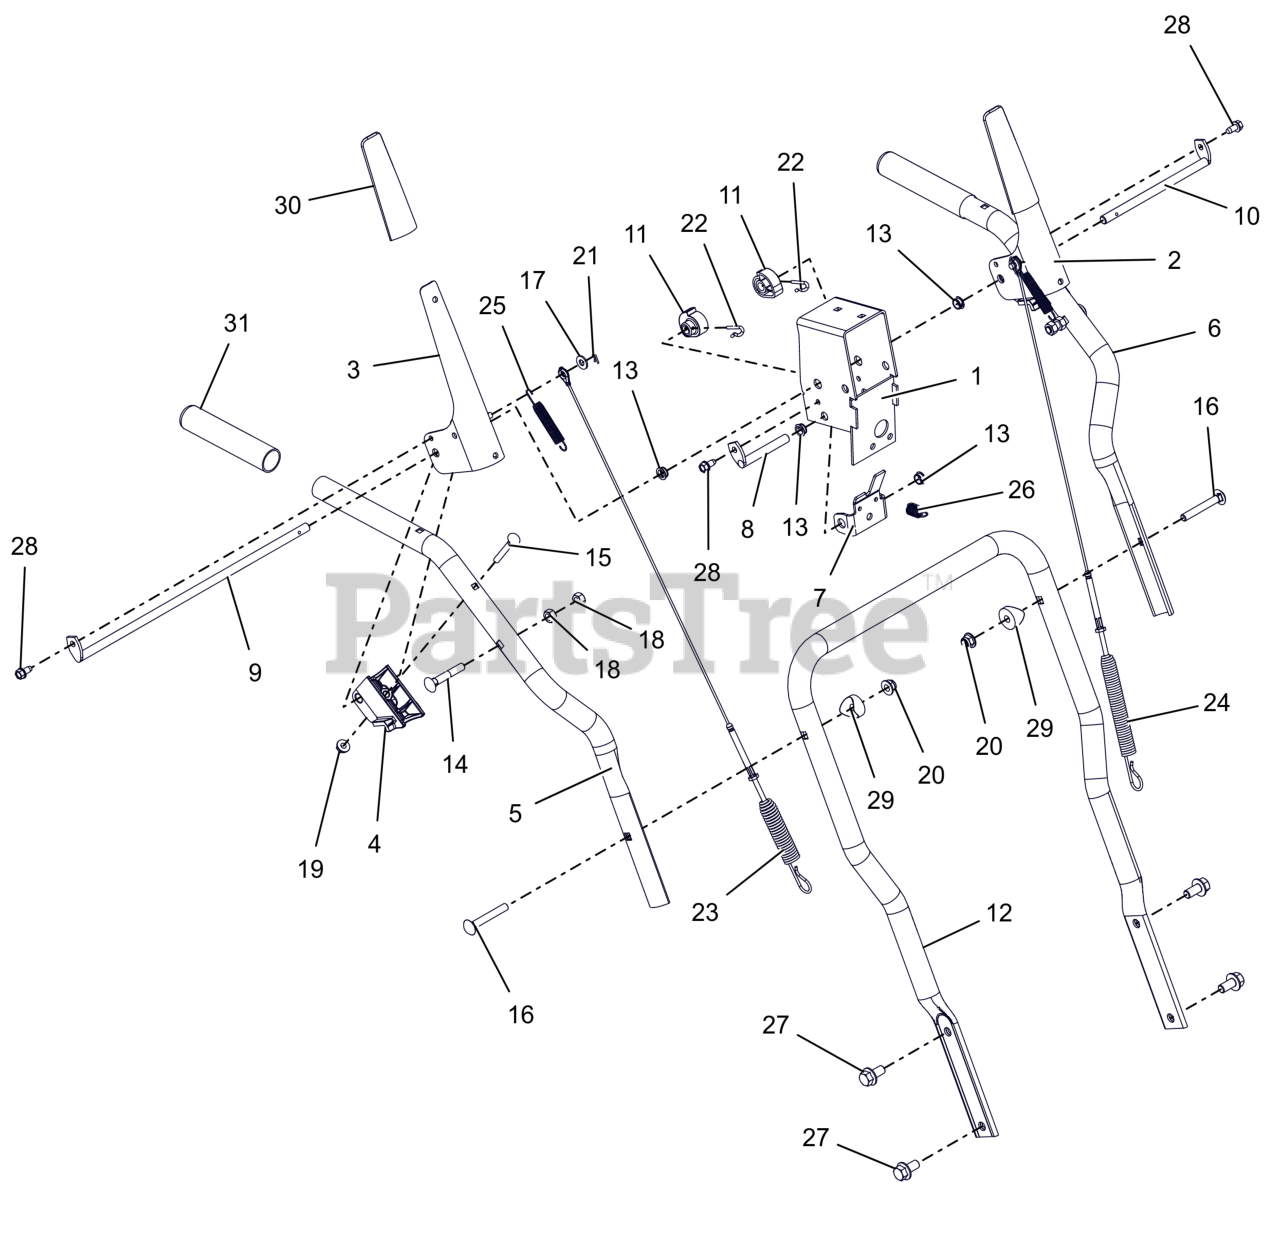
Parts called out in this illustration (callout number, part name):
1	WELDMENT, BRACKET INTERLOCK
2	LEVER, CLUTCH-LH
3	LEVER, CLUTCH-RH
4	BLOCK, CLUTCH PADDLE
5	HANDLEBAR, UPPER - RH (BLACK)
6	HANDLEBAR, UPPER - LH (BLACK)
7	BRACKET, INTERLOCK ARM
8	ROD, PIVOT - INTERLOCK
9	ROD, PADDLE MOUNT - LONG
10	ROD, PADDLE MOUNT - SHORT
11	CAM, INTERLOCK
12	HANDLEBAR, LOWER SMALL DASH (BLACK)
13	BUSHING, POLYLINER-.38 SNAPIN
14	BLT-RDHDXLSQNK .31-18X2.0 G5YZ
15	BLT-RDHDXLSQNK .25-20X2.0 G5YZ
16	BLT, RHSN .31-18X2.25 G5 ZCC
17	WSHR,FLT .281X.625X.065 ZCC
18	NUT,LK-CTR .31-18 GA ZCC
19	NUT-LK-TOP-FLG .250-20 GF ZCC
20	NUT,LK-NYL-FLG .31-18 G5ZC120
21	PIN, HAIR #178 .06X.77 ZCC
22	PIN, SPRING CLIP
23	CABLE, AUGER (DELUXE & PRO)
24	CABLE, UPPER TRACTION
25	SPRING, EXTENSION
26	SPRING-EXT .047X.438X1.45
28	SCR-TAP .25-20X.50 HWH ZCC
29	SPACER, HANDLEBAR
30	SLEEVE, CLUTCH PADDLE-GRAY
31	GRIP,HANDLE-GRAY
